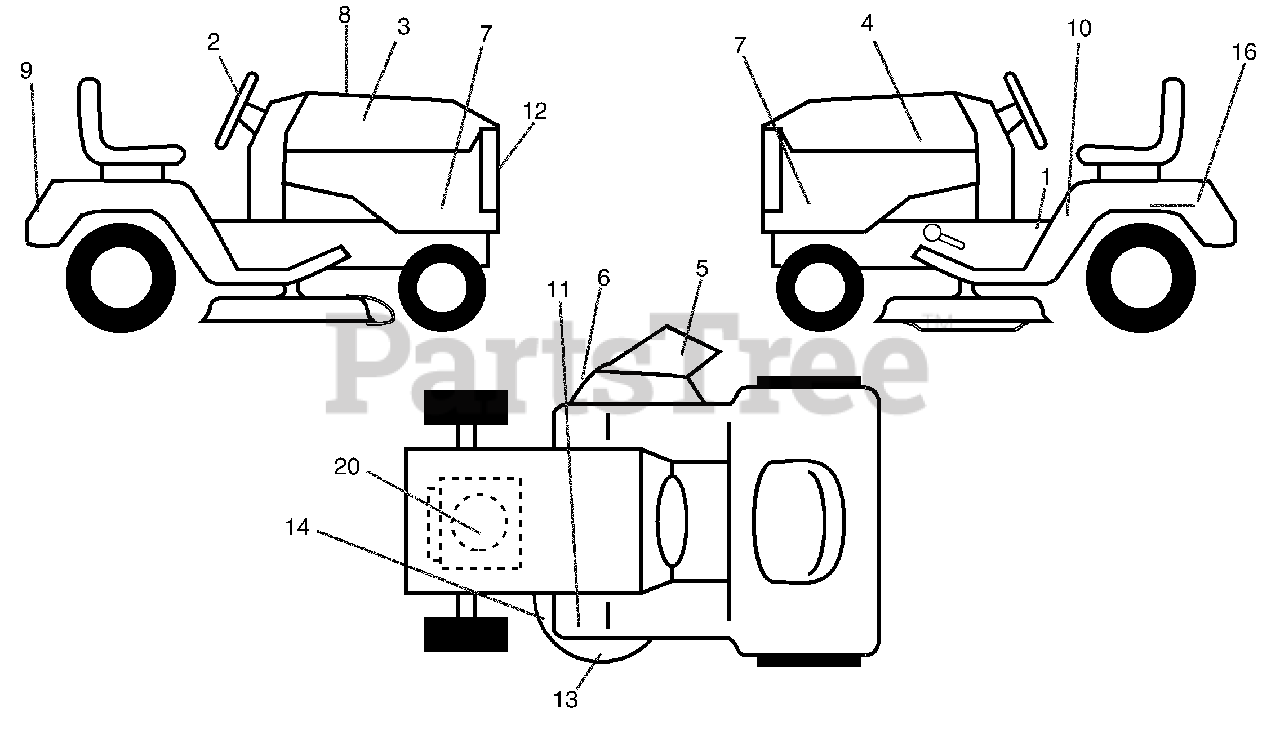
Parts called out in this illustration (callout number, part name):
1	Decal Instruction Operat English
2	Decal Steering
3	Decal Hood Rh
4	Decal Hood Lh
5	Decal Deck "B"
6	Decal Warning
7	Decal Side Panel
9	Decal Fender Logo
10	Decal Danger English
11	Decal Clutch/brake
12	Decal Grille
14	Decal V-belt Schematic 42"
16	Decal Battery Danger/Poison
20	Decal HP Engine
